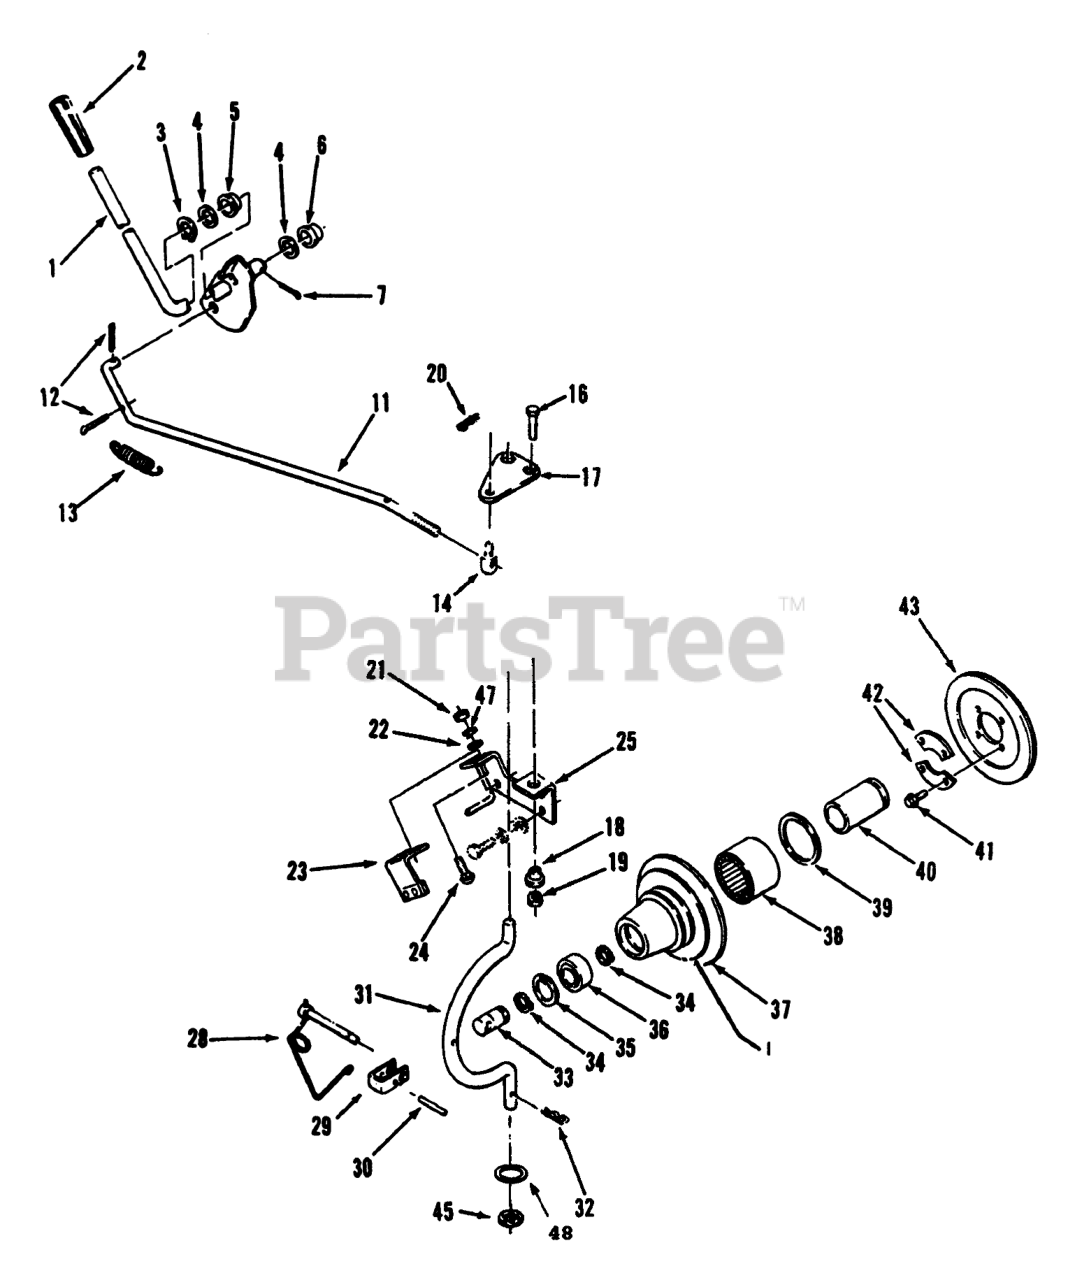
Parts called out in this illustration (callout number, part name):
1	Lever-Clutch,PTO
2	GRIP
3	RING-EXT GRIP
4	SHIM-WASHER
5	BUSHING-NYLINER
6	NYLINER BUSHING
7	PIN-COTTER
11	ROD-PTO CLUTCH
12	PIN-COTTER
13	SPRING
14	TRUNNION
16	SCREW-HH
17	PLATE
18	SPACER-LIFT LINK
19	NUT-LOCK, NI
20	Hairpin Cotter
21	NUT-HEX
22	WASHER-FLAT
23	ASM-Bracket
24	SCREW-CARR
25	Bracket-Engine
28	LOCKING PIN ASM
29	CLEVIS
30	Pin-Spirol 5/32 x 1-3/8
31	ROD-HOUSING
32	Hairpin
33	SHAFT-PTO
34	Ring-Snap
35	Ring-Snap 1-3/4 Internal
36	BEARING-BALL
37	Housing-Clutch
38	Seal
39	BRG-NEEDLE OPEN END
40	RACE-BEARING
41	H H C S
42	RETAINER
43	Facing-Clutch
45	RING-REINFORCED CIRC
47	WASHER-LOCK
48	Washer-Flat
